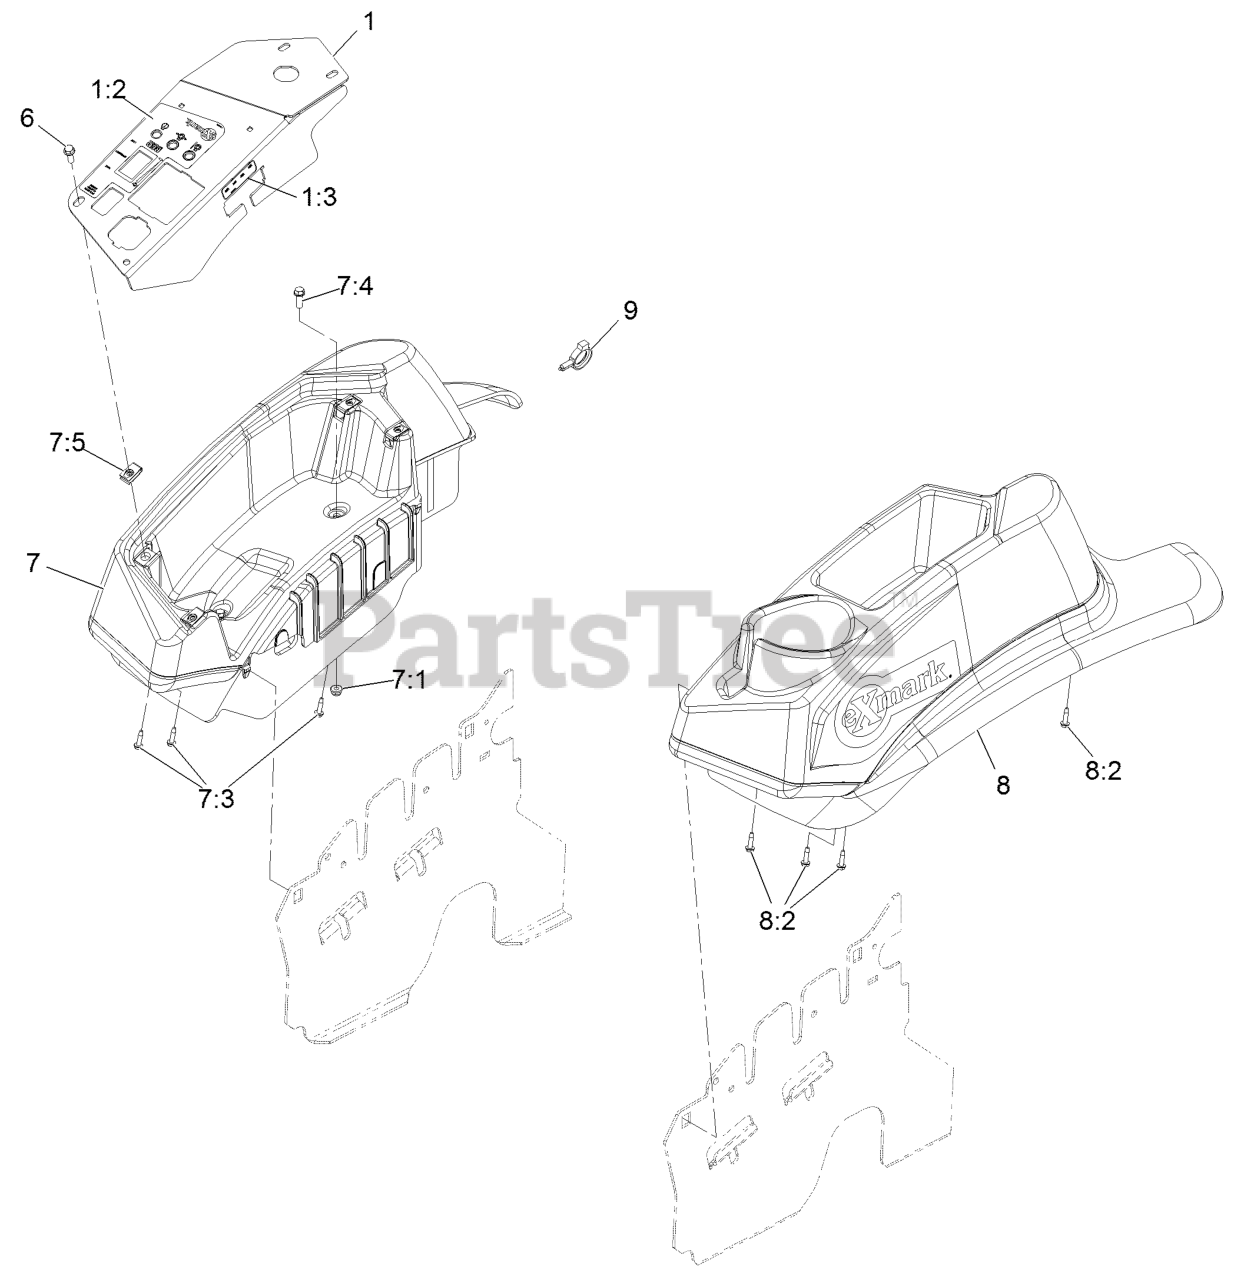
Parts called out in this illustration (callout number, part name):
1	CONTROL PANEL W/DECAL
1:2	Decal-E-Gov Control
1:3	DECAL-FUSE
6	SCREW-HWH
7	CONSOLE,RH NARROW ASM
7:3	SCREW,THD FORM,HWH
7:4	SCREW-HWH
7:5	Nut-Retainer-Panel 1/4-20
8	CONSOLE.LH NARROW ASM
8:2	SCREW,THD FORM,HWH
9	CLAMP-HOSE
